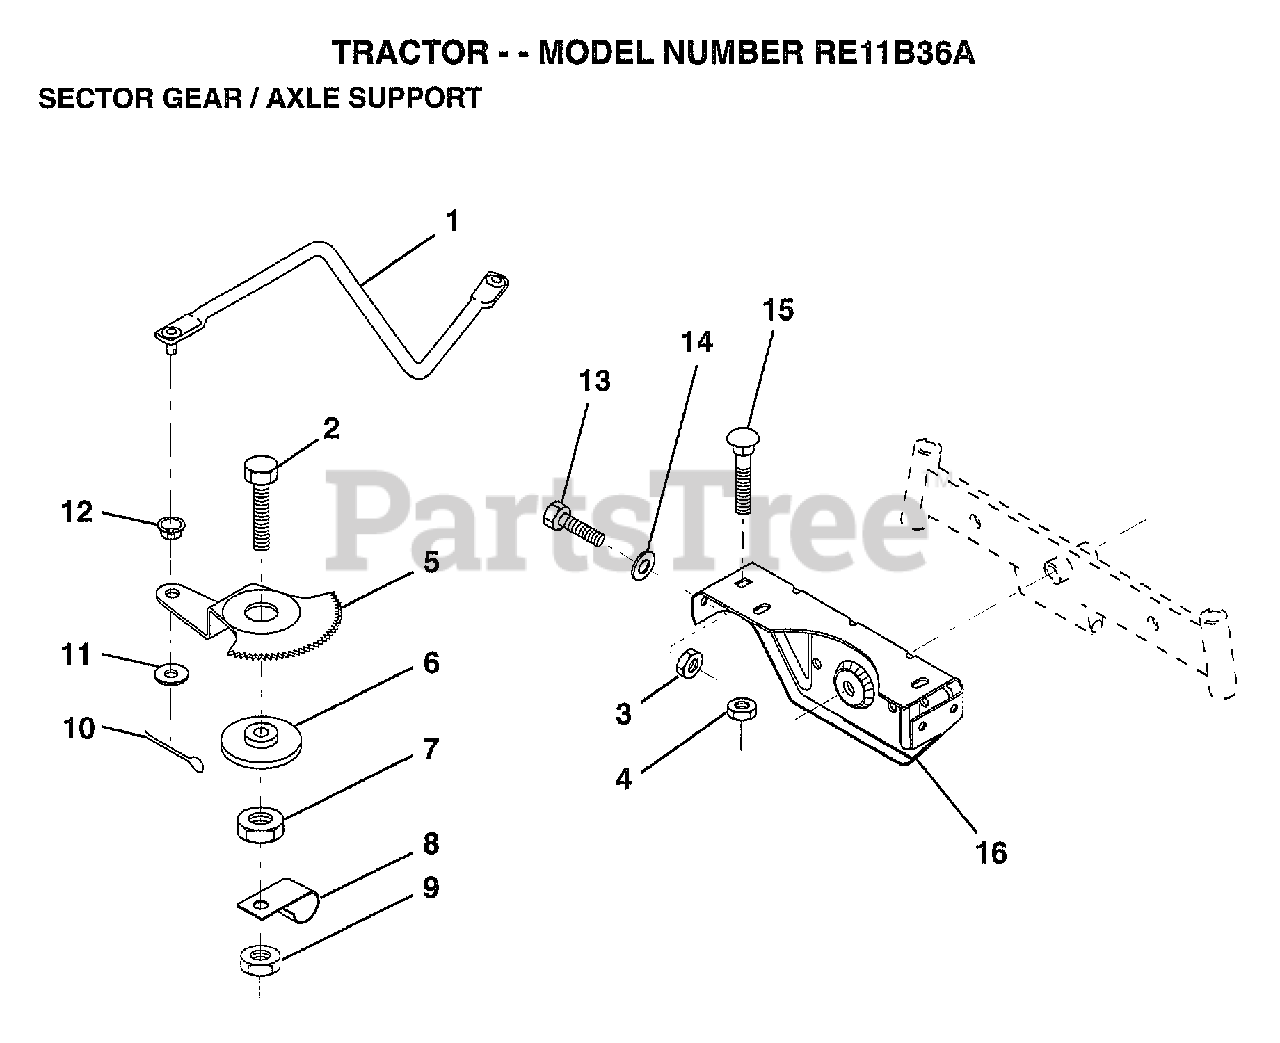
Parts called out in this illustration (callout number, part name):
1	DRAG LINK
2	"BOLT,HEX"
5	GEAR SECTOR
6	BUSHING
7	NUT
8	CLIP INSULATOR
9	NUT LTV
10	COTTER PIN
11	WASHER
12	BUSHING.DRAGLINK
13	BOLT
14	WASHER
15	BOLT
16	SUPT AXLE FRONT
